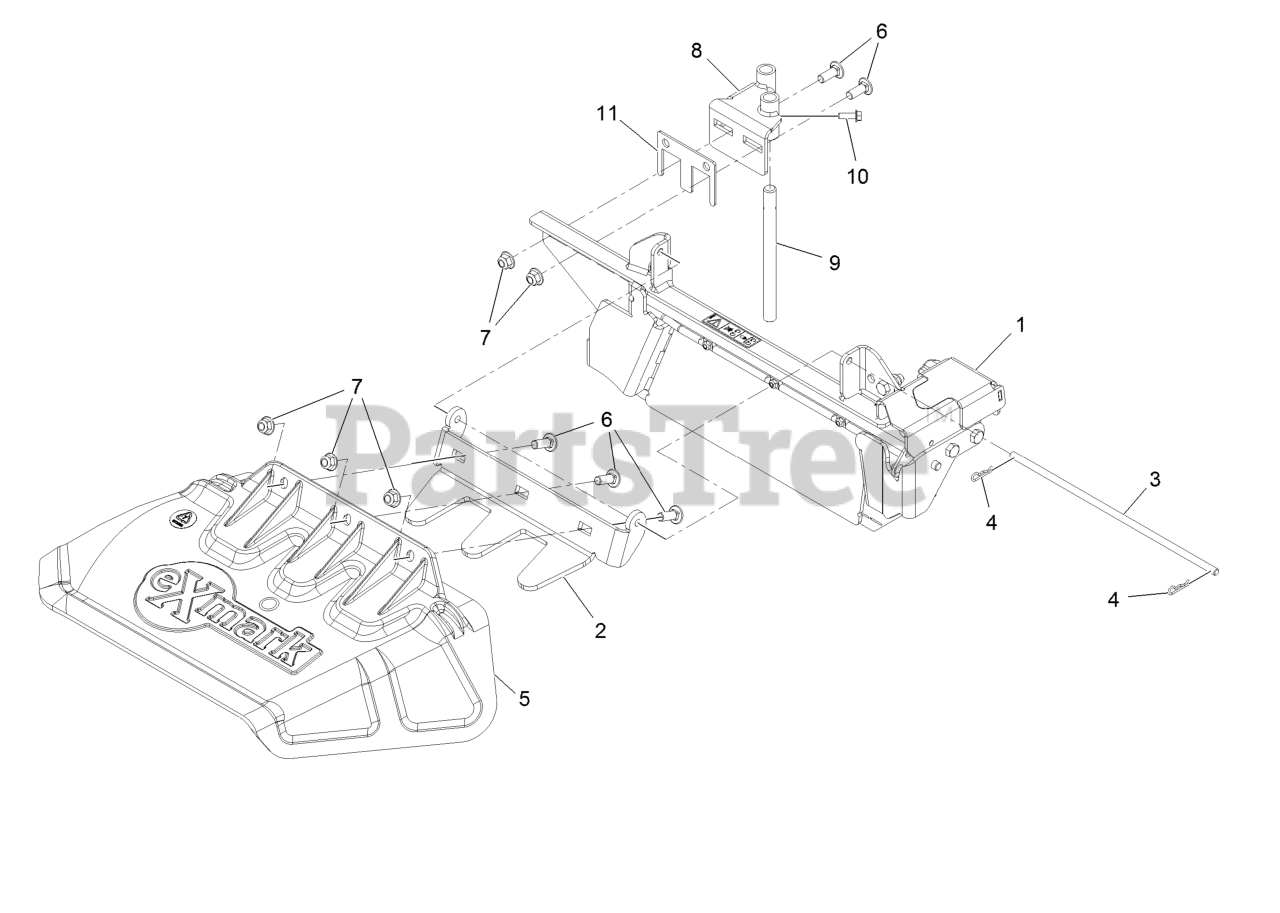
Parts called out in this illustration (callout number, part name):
1	ASM, Ocd Gate
2	Mount, Discharge Chute
3	Pin,Chute
4	Hairpin-Cotter
5	Chute, Discharge
6	Bolt-Carriage 3/8-16 X 1
7	Nut-Nyloc 3/8-16 Flg
8	Weldment, Ocd Mount
9	Pin-Mount, Ocd
10	Screw-Hex Flange 1/4-20 X 3/4
11	Shim-Ocdwb
